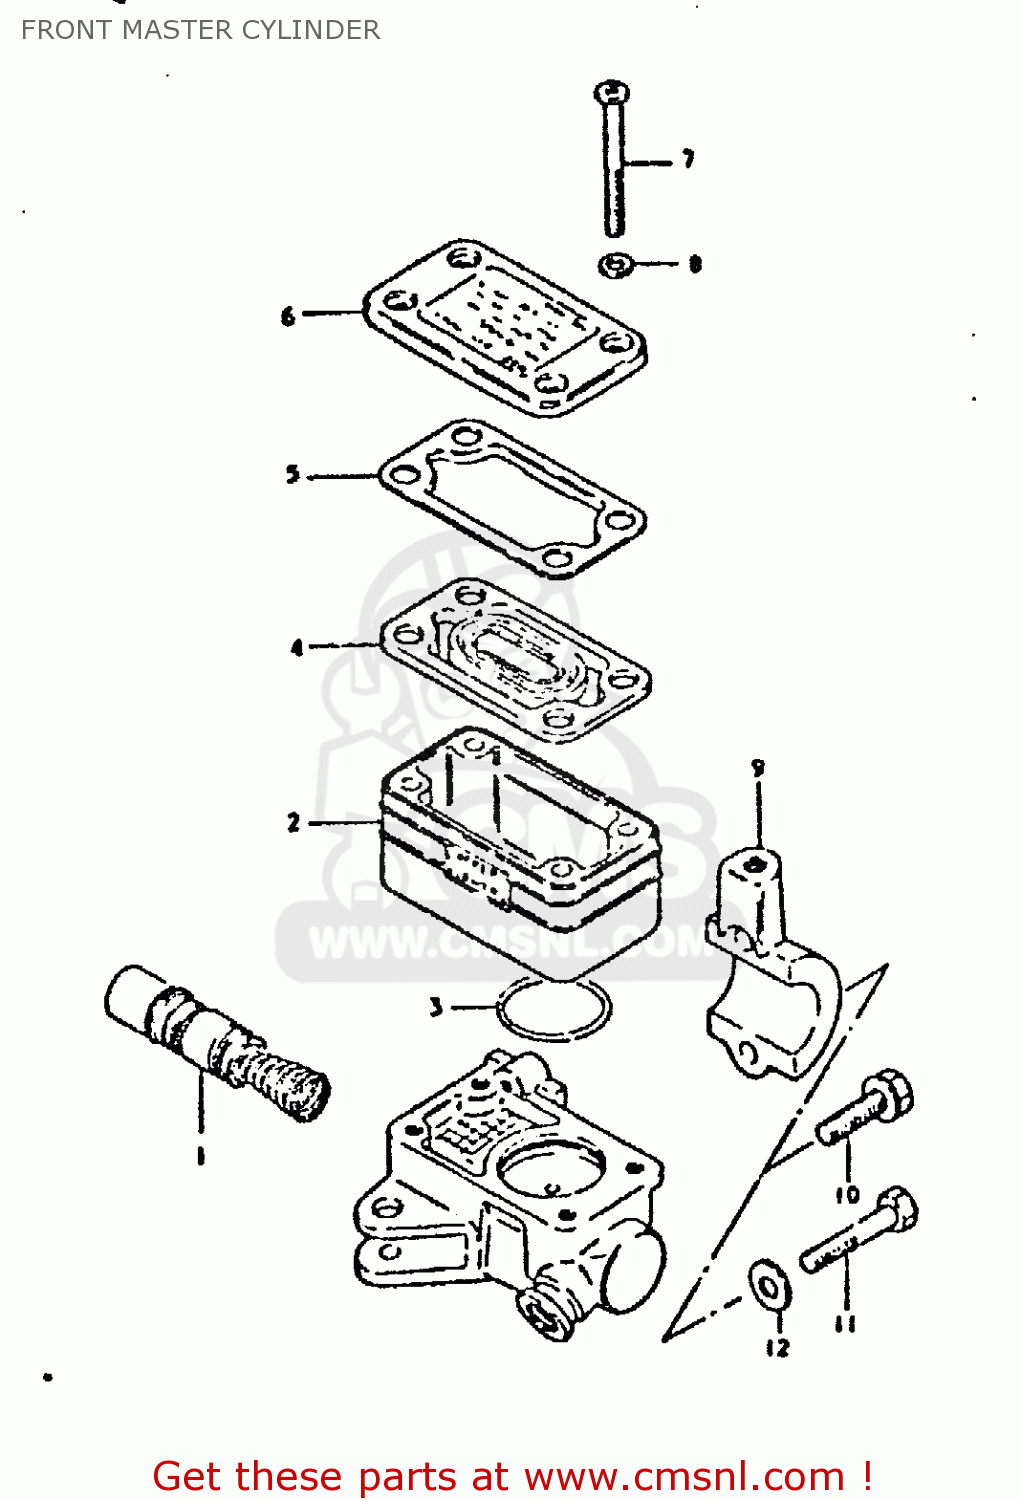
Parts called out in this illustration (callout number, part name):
1	PISTON & CUP SET
2	RESERVOIR
3	O RING
4	DIAPHRAGM
5	PLATE,DIAPHRAGM
6	CAP
7	SCREW
8	WASHER
9	HOLDER
10	BOLT,MASTER CYLINDER H
11	BOLT
12	WASHER
